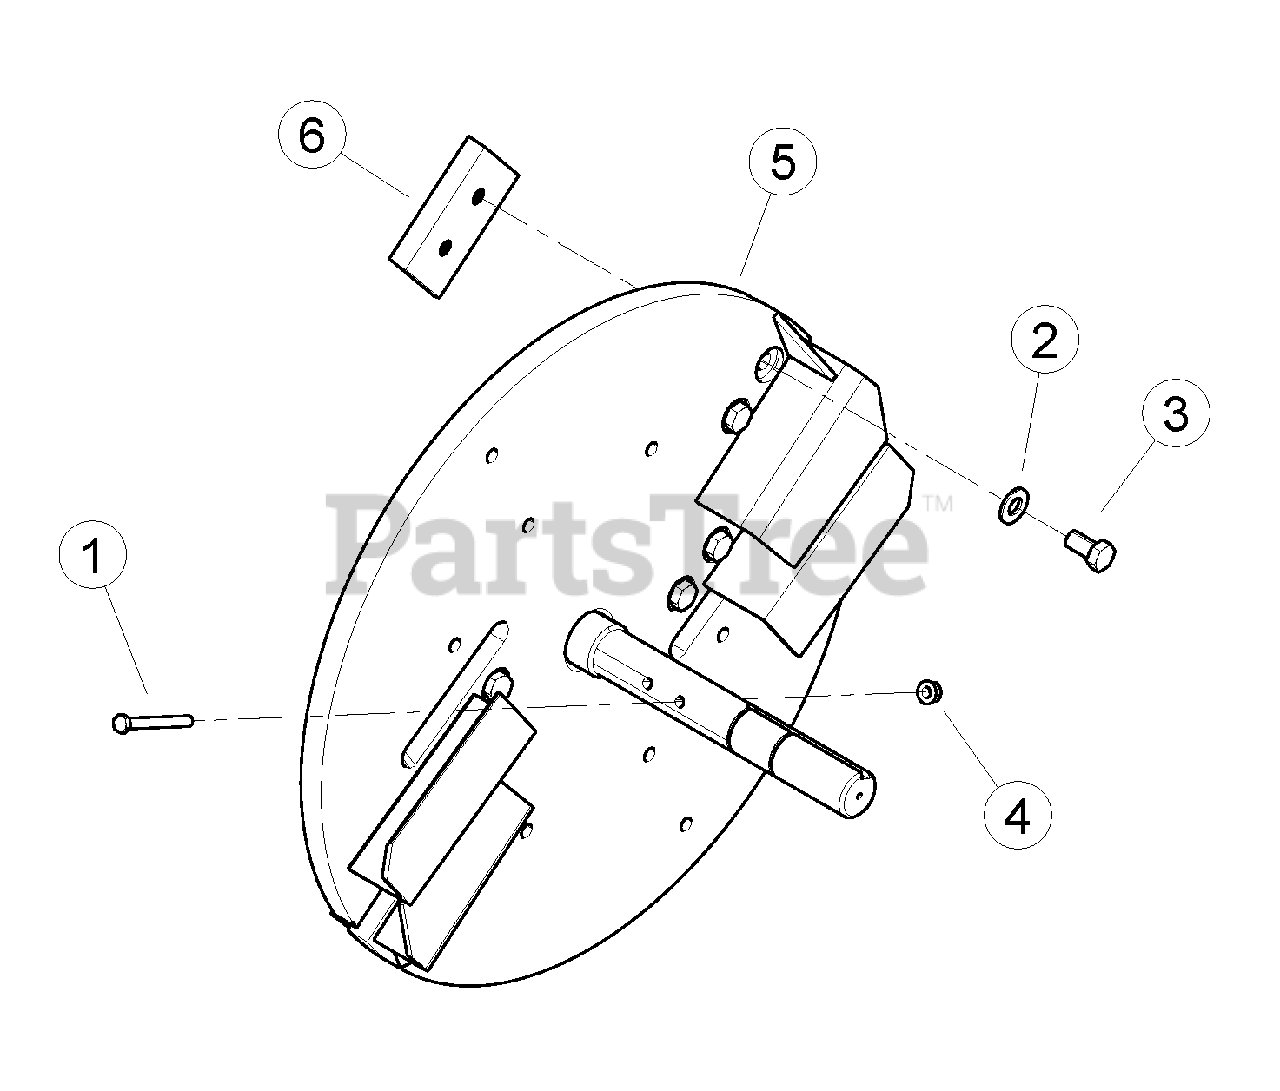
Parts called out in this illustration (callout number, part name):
1	BOLT, 3/8 X 3-1/2 FULL THD ZP GR5
2	WASHER, 5/8 SAE HARDENED
3	BOLT, M16 X 2.0 X 30 HEX HD W/ PATCH
4	NUT, 3/8-16 NYLOCK FLANGE
5	WELDMENT, 6 CHIPPER ROTOR
6	KIT, CHIPPER BLADE
